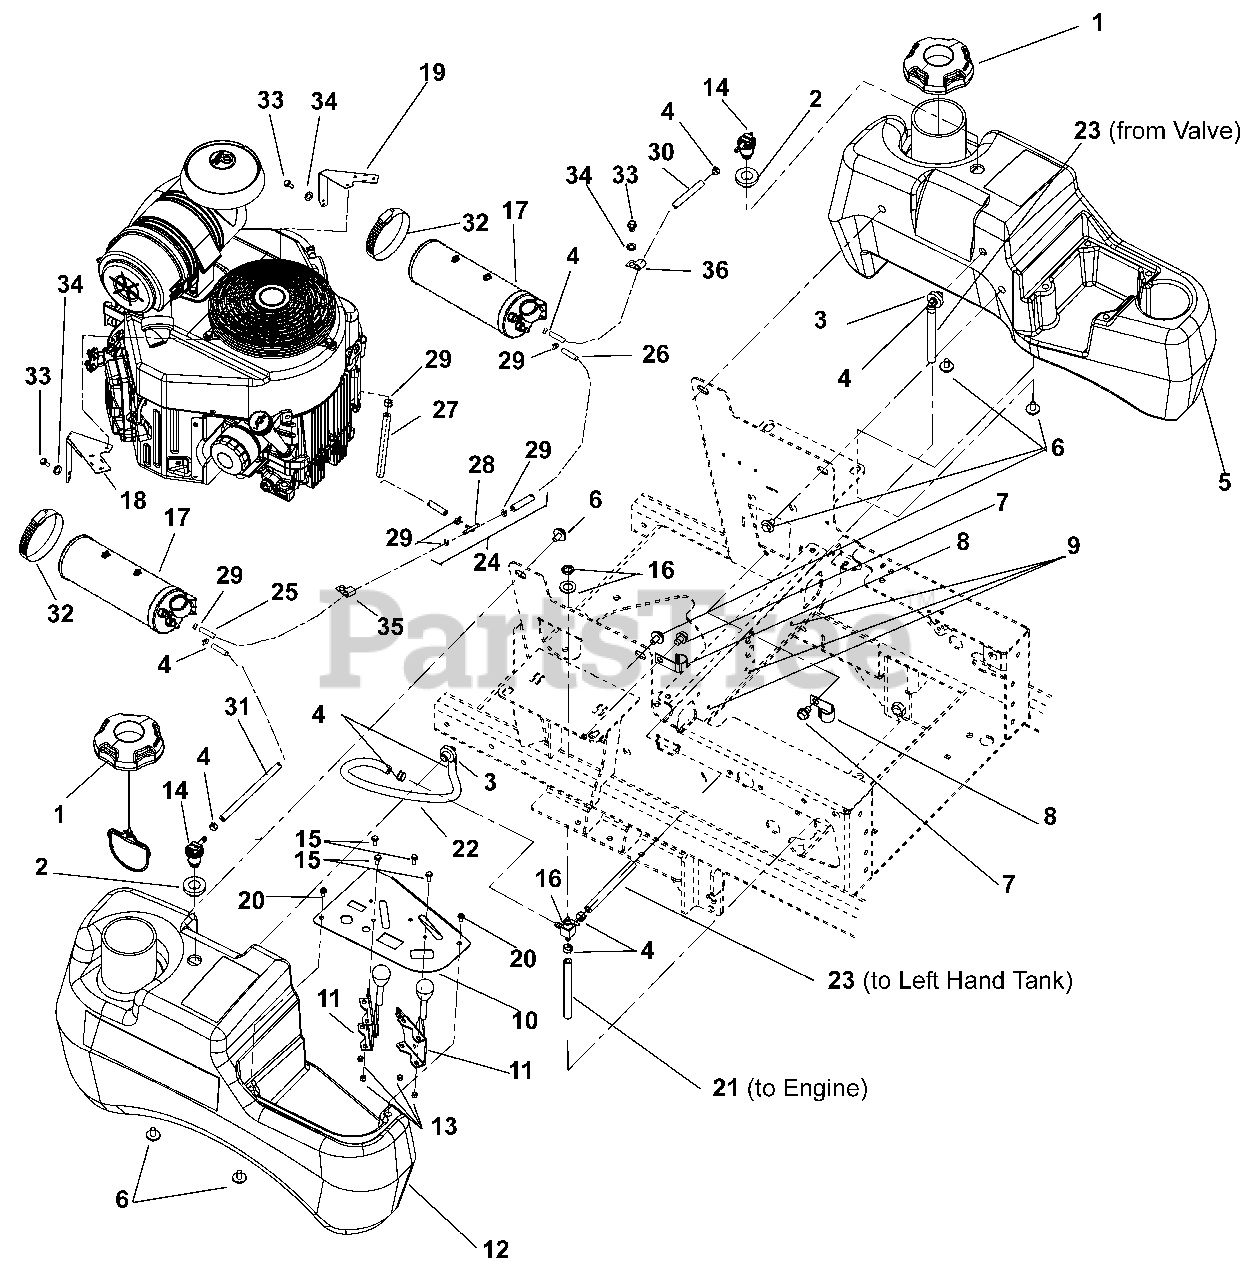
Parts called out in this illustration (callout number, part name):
1	Cap, Fuel Non-Vent Autolock
2	Grommet, Remote Vent Nitrile
3	Assembly, Medium Tank Fuel Pick-Up
4	Clamp, Fuel Line
5	Tank, Left Hand Medium Gravely Fuel
6	Bolt, SEMS .31-18 x .62
7	Screw, Tapping Hex Washer Head Thread Rolling .38-16 x .50
9	Cable Tie
10	PT100 Control Panel, Black
11	Cable, PT100 Throttle Control
12	Tank, RH Medium Gravely Fuel
13	Nut, Locking, Nylon 10-24 w/Insert
14	Valve, Combination
15	Screw, Machine Hex Washer Head 10-24 x .50
16	Valve, Fuel
17	Canister, Carbon 400cc
18	Bracket, Mount PT100 Carbon Canister Right Hand
19	Bracket, Mount PT100 Carbon Canister Left Hand
20	Screw, Machine HWH Stainless 10-24x.38
21	Hose, .25 Low-Perm Bulk Gas (to engine)
22	Hose, .25 Low-Perm Bulk Gas (to right hand tank)
23	Hose, .25 Low-Perm Bulk Gas (to left hand tank)
24	Assembly, Fuel Valve PT100 CARB (includes items 25-29)
25	Hose, .188 Low-Perm Bulk Gas
26	Hose, .188 Low-Perm Bulk Gas
27	Hose, .188 Low-Perm Bulk Gas
28	Assembly, Fuel Line PT100 CARB
29	Clamp, Hose Spring .188
30	Hose, .25 Low Perm Bulk Gas
31	Hose, .25 Low Perm Bulk Gas
32	Clamp, Hose Worm 2.3/3/2 SS #44
33	Bolt, Hex M8-1.25 x 20
34	Washer, Lock .31 x .078 Reg
35	Clamp, Cushioned Steel
36	Clamp, Cushioned Steel .75
